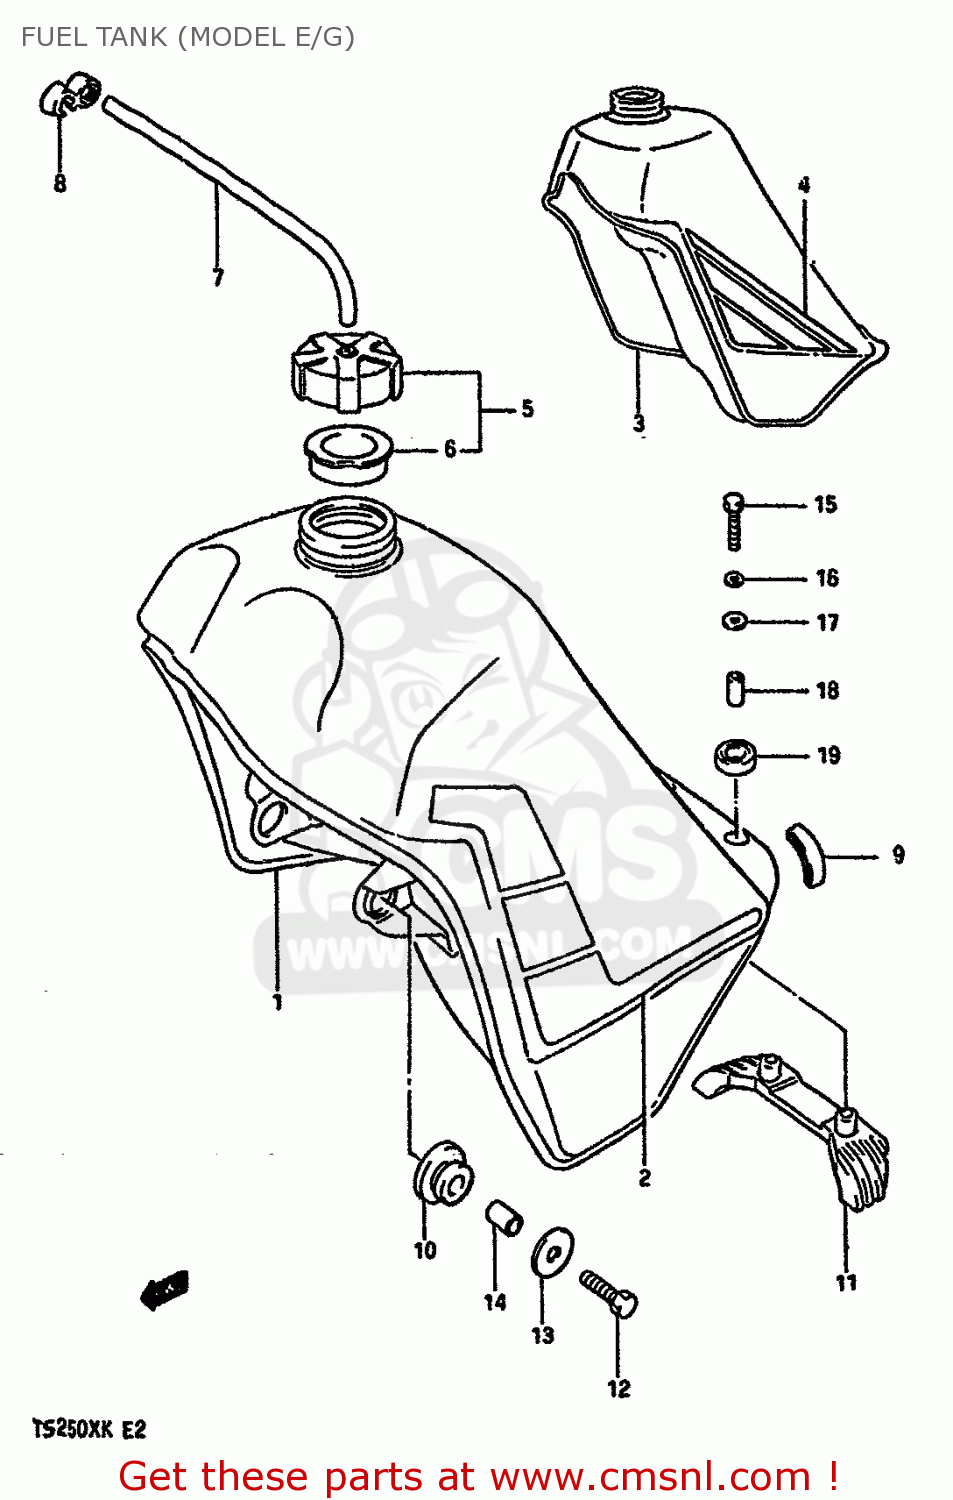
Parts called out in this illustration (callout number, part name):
1	TANK ASSY,FUEL (RED)
2	TAPE SET,FUEL TANK
3	TANK ASSY,FUEL (RED)
4	TAPE SET,FUEL TANK
5	CAP SET,FUEL TANK
6	GASKET (NAS)
7	HOSE
8	CLAMP,FUEL TANK BREATHER HOSE
9	MOLDING,FUEL TANK
10	CUSHION,FUEL TANK FRONT
11	CUSHION,FUEL TANK REAR LOWER
12	BOLT (8X30)
13	WASHER
14	SPACER (8.6X12X17.5)
15	BOLT
16	WASHER,LOCK
17	WASHER, LOWER
18	SPACER
19	CUSHION
